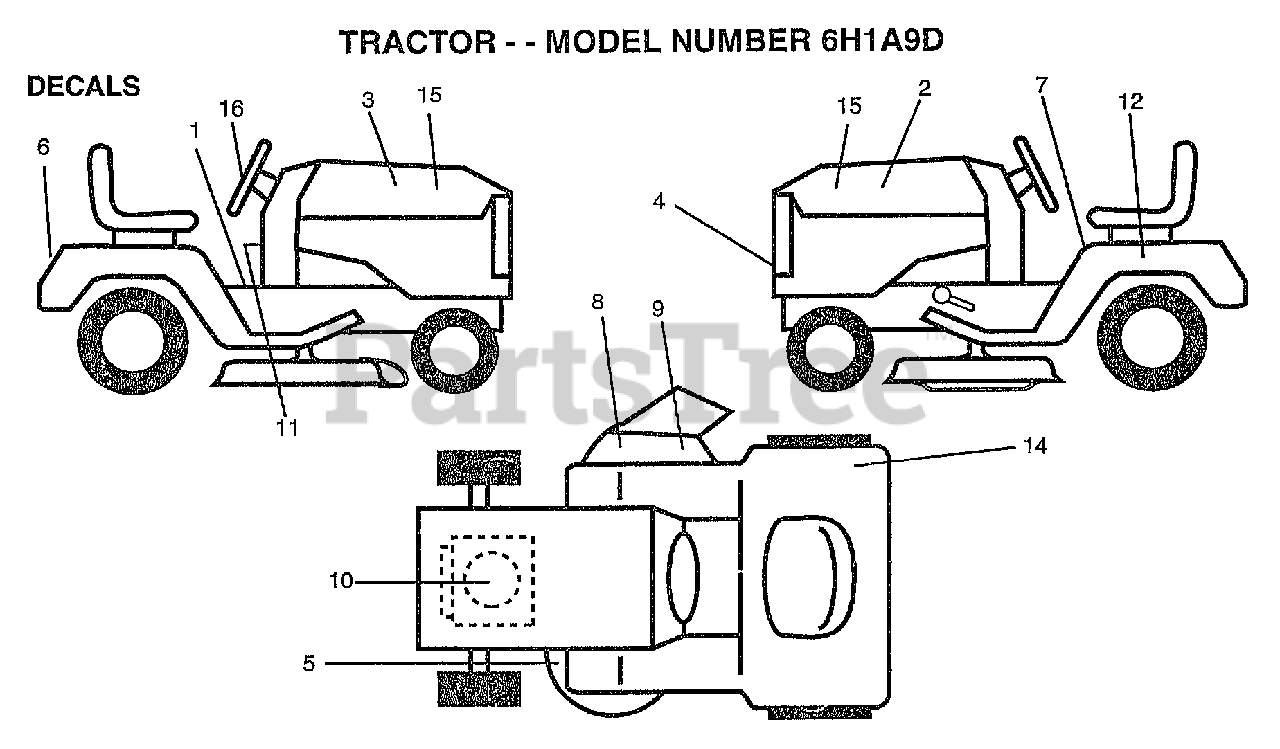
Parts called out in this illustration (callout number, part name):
1	DECAL.OP.INST.SYM
2	DECAL HD RLY LH
3	DECAL HD RLY RH
4	GRILL DECAL
5	DECAL.V.BELT
6	FENDER DECAL
7	DECAL.READ.O.MANU
8	DECAL.DANGER.CUTF
10	DECAL, HP ENGINE
11	DECAL.EURO.ST.CE.
12	DECAL.BTRY.DANGER
15	DECAL.HOOD.12.5
16	"DECAL,STR WHL"
